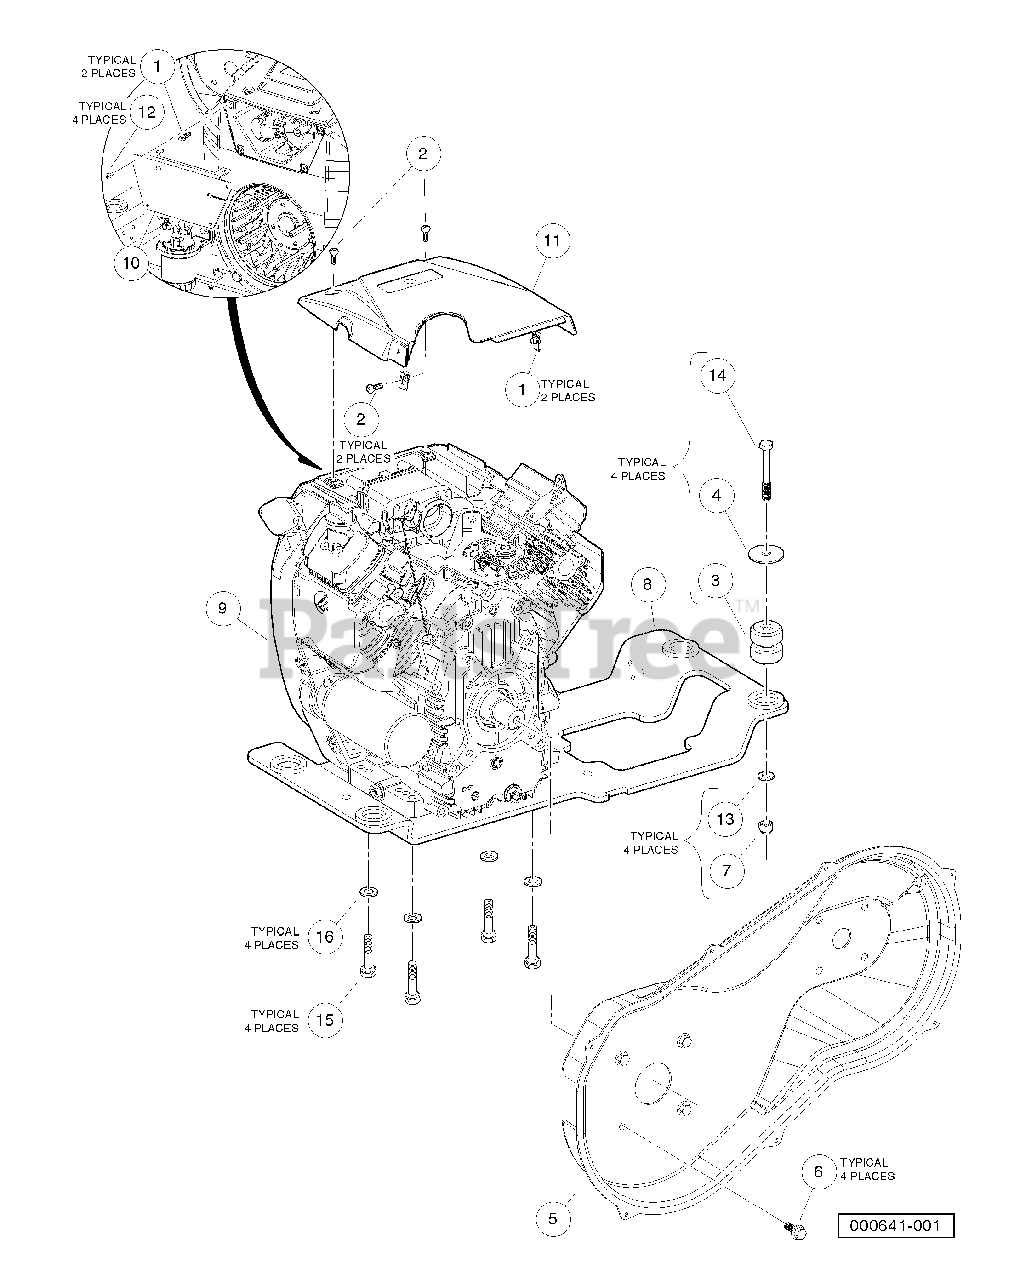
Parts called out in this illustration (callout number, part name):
1	U-nut, M6-1.0 Prev Torque
2	Screw, M6 Torx Bttn Hd Sems
3	Isolator Ring and Bushing
4	Washer, Snubbing, Ring N Bush
5	Cover, CVT Inner, FH680D
6	Bolt Flanged Head, 3/8-16x1.0 with Loctite
7	Locknut, M12x1.75 Nylon Insert
8	Weldment, Eng Mnt, Kaw, Fh680d
9	Engine, Kawasaki, FH680D
10	Engine, Front Cover, Fh680d
11	Cover, Engine, Top
12	Screw, Pn Hd Blk, 10-16 X .625
13	Washer, M12 Hard
14	Bolt, M12 X 1.75 X 90
15	Bolt, M10 X 1.5 X 60
16	Washer, M10 Hard
